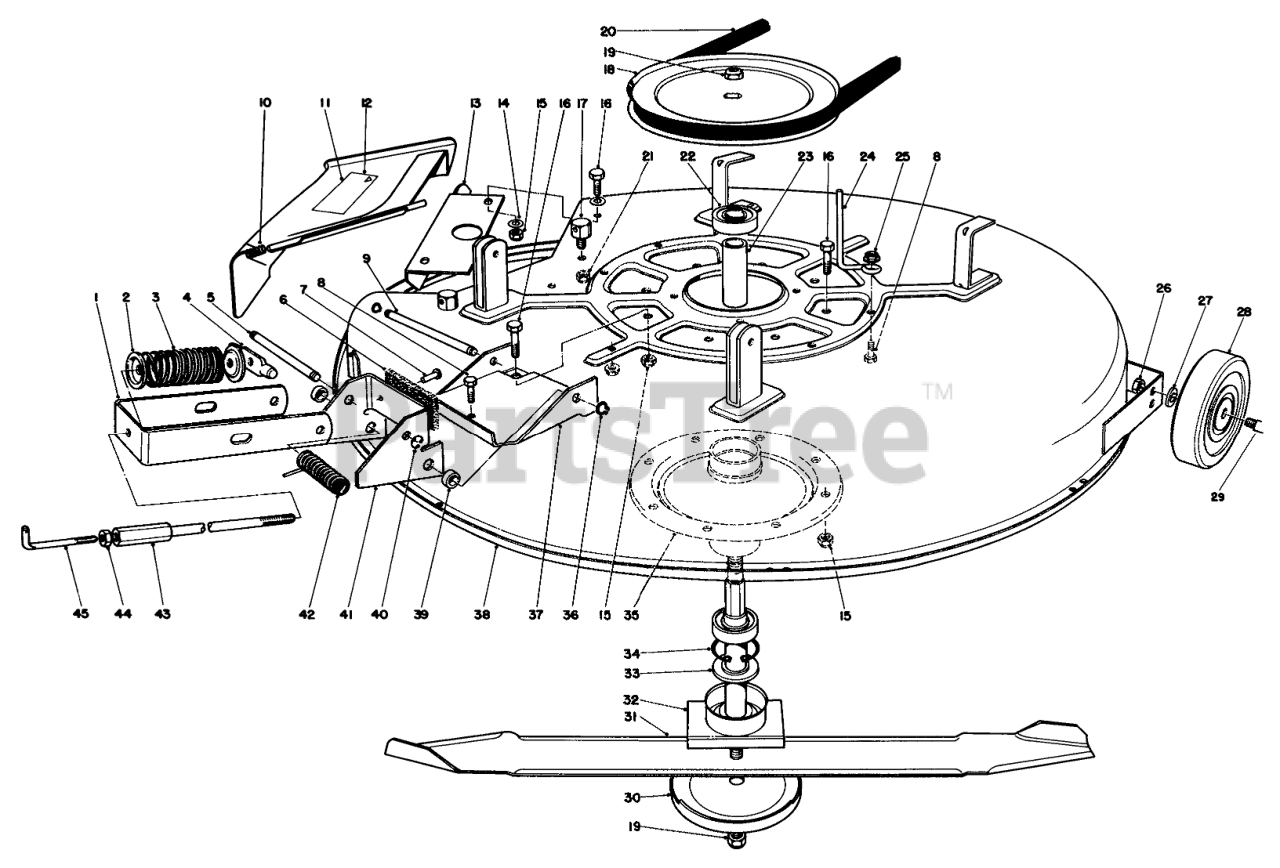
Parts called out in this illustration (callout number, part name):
1	Bracket-Engagement
2	RETAINER-SPR. TOP
3	SPRING-COMPRESSION
4	SHAFT-DECK ADJ.
5	Pin-Clevis
6	BRAKE PAD
7	RIVET .187 X 7/16 BRASS
8	SCREW-HH
9	CLEVIS PIN
10	SPRING
11	Deflector Assembly (Incl. Ref. #12)
12	Decal
13	Baffle Deck
14	WASHER-PLAIN
15	NUT-LOCK, NI
16	SCREW-HH
17	POST-PIVOT
18	PULLEY
20	V-BELT, DECK
21	NUT-LOCK, SIDE
22	BEARING-BALL
23	Spacer-Bearing
24	BELT GUIDE
25	NUT-LOCK, HHF
26	Nut
27	WASHER-FLAT
28	DECK WHEEL
30	Cup
31	Blade
32	SPINDLE SHAFT WA
33	SPACER-SPINDLE
34	RING-RETAINING
35	Spindle Body
36	RING-RETAINING
37	DECK ENGAGE CHANNEL R
38	Cutter Deck
39	DECK BRAKE SPACER
40	E-RING
41	Support Deck Brake Assembly (Incl. Ref. #6 & 7)
42	SPRING
43	ADJ HUB WA
44	NUT-JAM
45	ADJ. ROD
